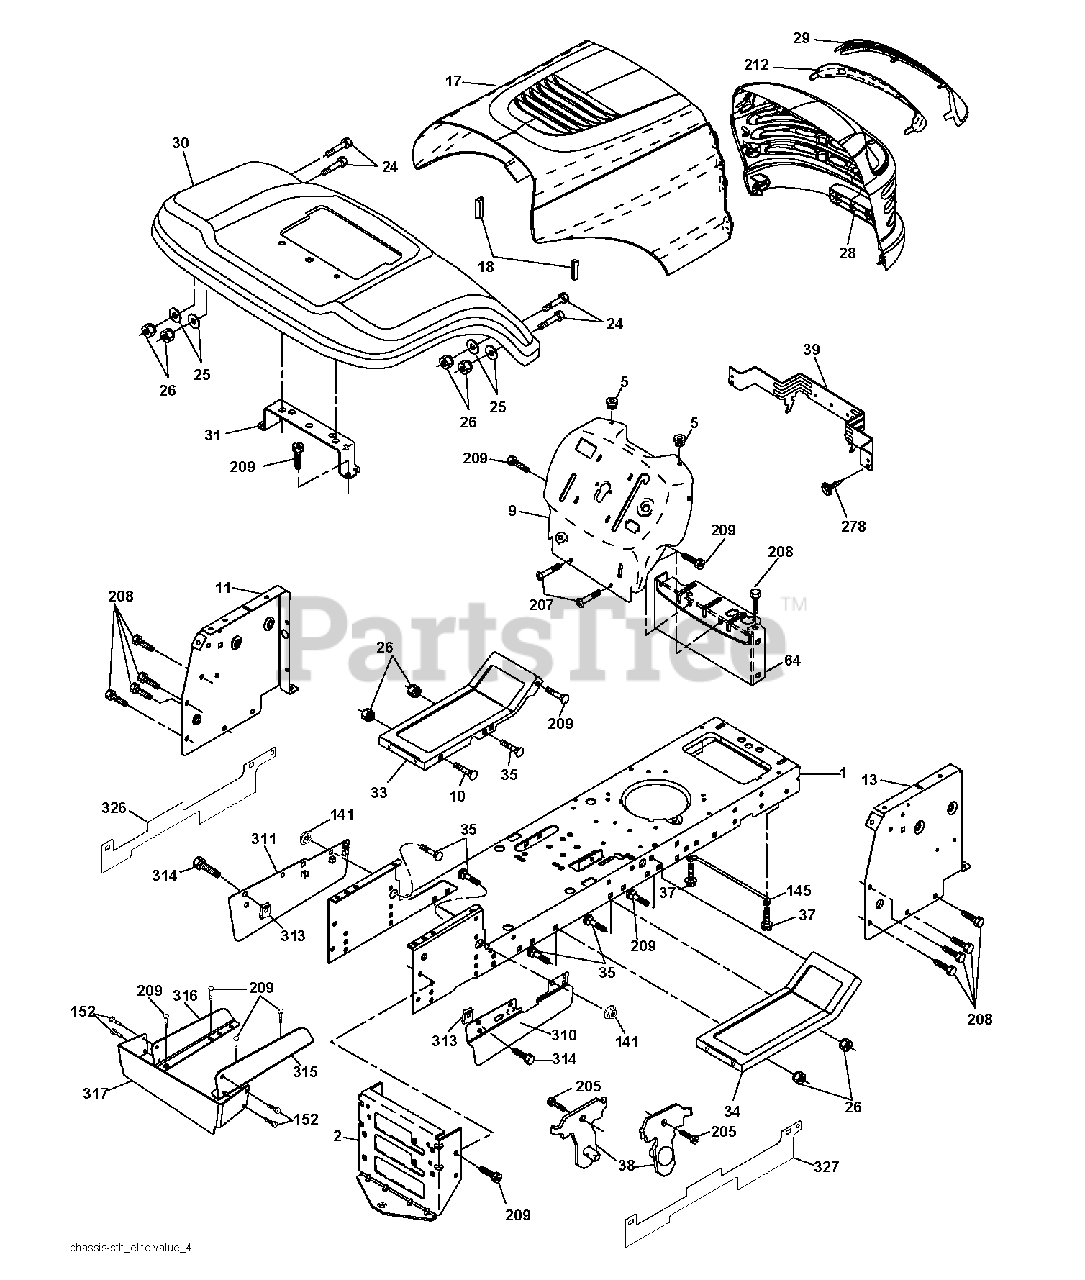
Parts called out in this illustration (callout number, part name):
1	CHASSIS STAMPING
2	DRAWBAR, 12GA
5	BUMPER.RUBBER.HOOD
10	BOLT D
11	PANEL.DASH.LH.LTX
18	BUMPER.HOOD.LARGE.1.75"
25	WASHER
26	NUT
31	BRACKET FENDER
38	BRACKET.ASM.PIVOT.MOWER.REAR
39	BRACKET PIVOT
64	DASH LOWER
141	NUT LOCK FLG 3/8-16 UNC
145	ROD.PIVOT.HOOD
152	SCREW
207	SCREW, 5/16-18 X 1/2
208	SCREW 3/8-16X1/2
209	SCREW, 3/8-16X3/4
278	SCREW.#10 X 0.750.BOS THREAD
314	SCREW.1/4-20X5/8
